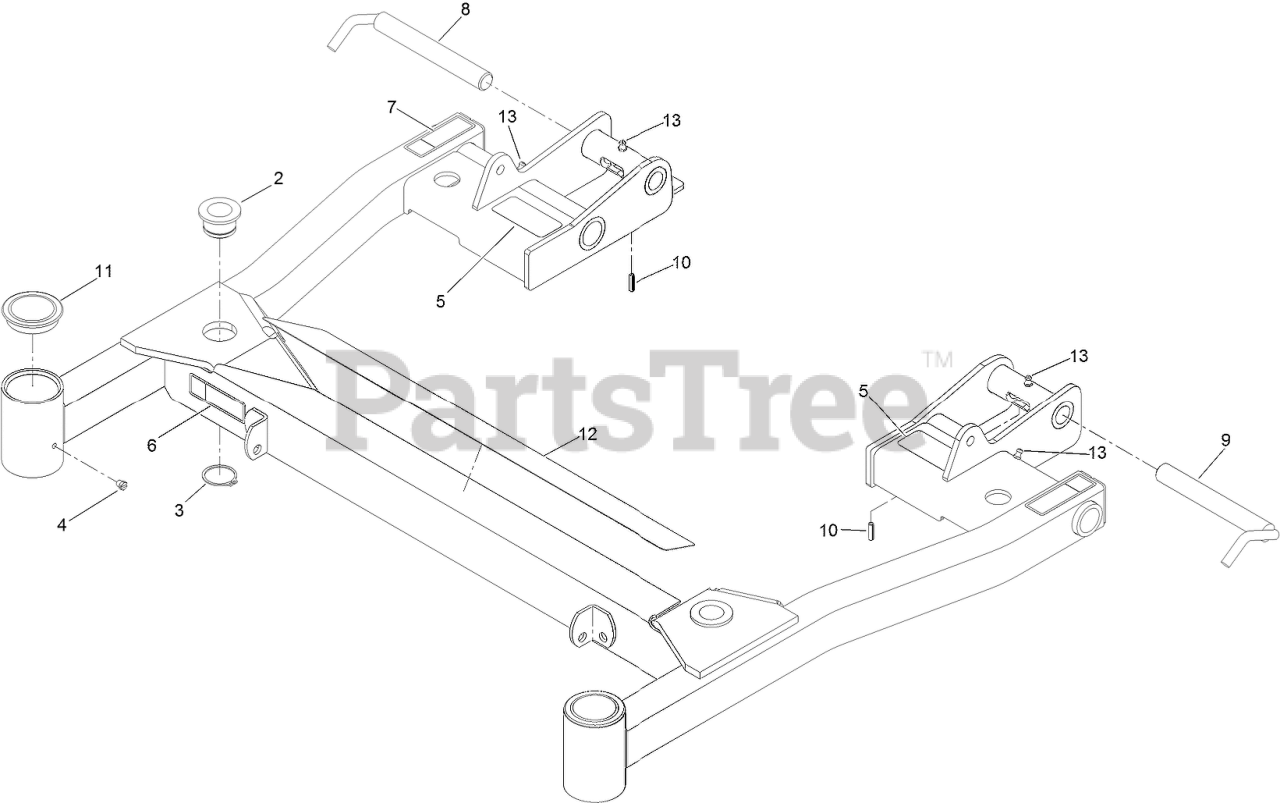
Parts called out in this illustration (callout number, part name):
2	BUSHING-SUPPORT, DECK
3	RING-RETAINING
5	DECAL-WARNING
6	DECAL-DANGER
7	DECAL-WARNING, FOLDING DE
8	LOCK-DECK, RH
9	LOCK-DECK, LH
10	PIN-SPRING
11	CAP-GREASE
12	PAD-SKID, ANTI
13	FITTING-GREASE
